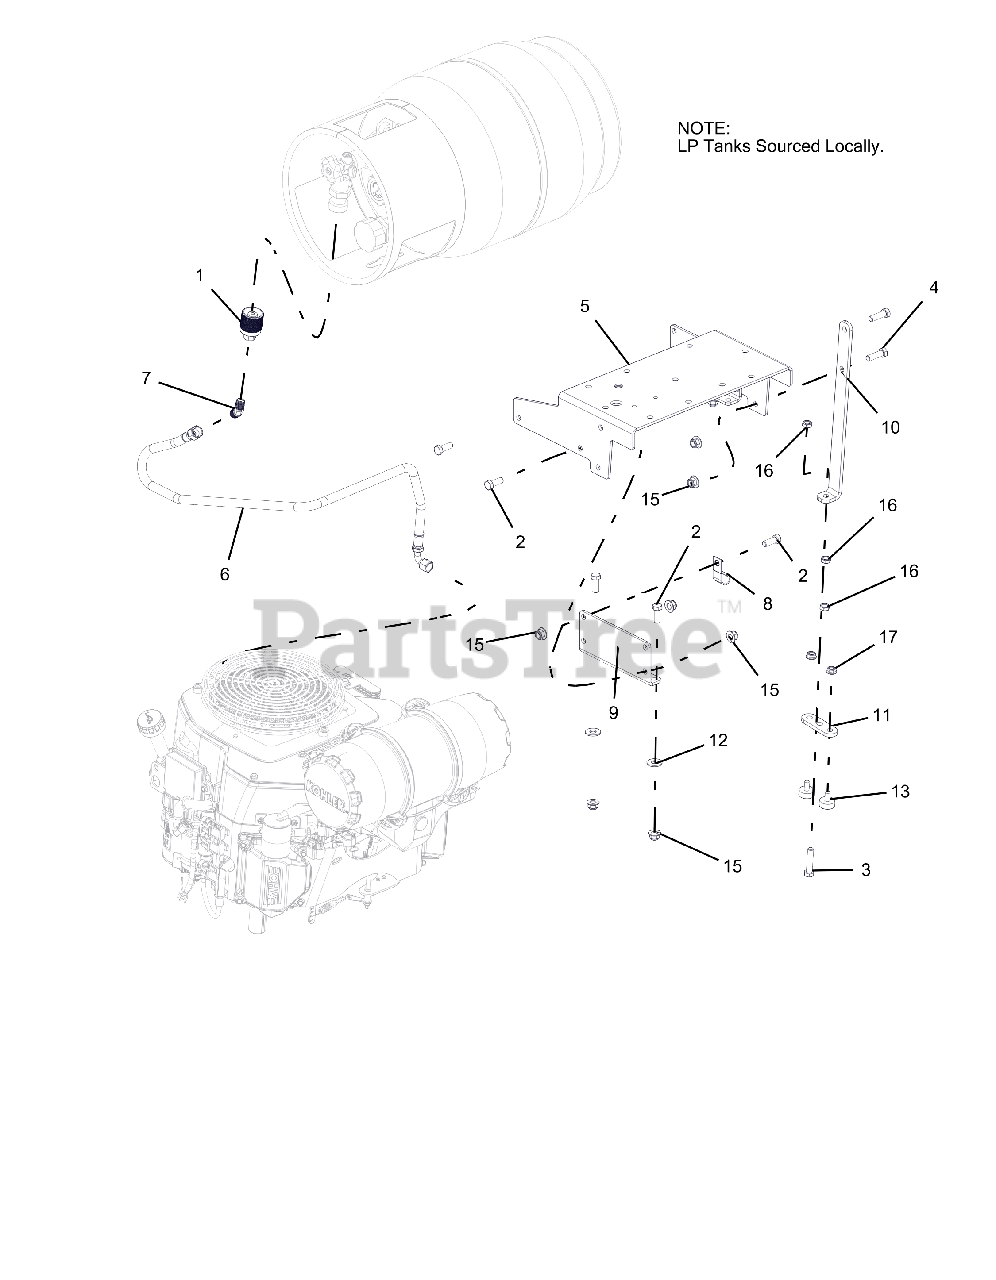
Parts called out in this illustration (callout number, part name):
1	FTG, LPG TANK COUPLER -LH THRD
2	BLT-HEX .38-16X1.00 GR5 YWZC
3	BLT-HEX .38-16X1.75 GR5 YWZC
4	BLT-HEX .38-16X1.25 GR5 YWZC
5	SUPPORT, TANK
6	HOSE, LPG SS25UL 6-4-6-30.00
7	FTG, 45° 1/4-NPTF 9/16-18 45 FLG
8	P-CLIP, .500 INSULATED
9	MOUNT, TANK
10	STAND, TANK SIDE
11	BAR, FOOT
12	WSHR-FL-STL.438X1.00X.083 YWZC
13	BUMPER, RUBBER
14	BLT-HEX .38-16X1.00 GR5 YWZC
15	NUT-LK-NYL-FLG .38-16 YWZC
16	NUT, JAM .375-16 YWZC
17	@NUT-SPNLK-FLG .312-18 YWZC
